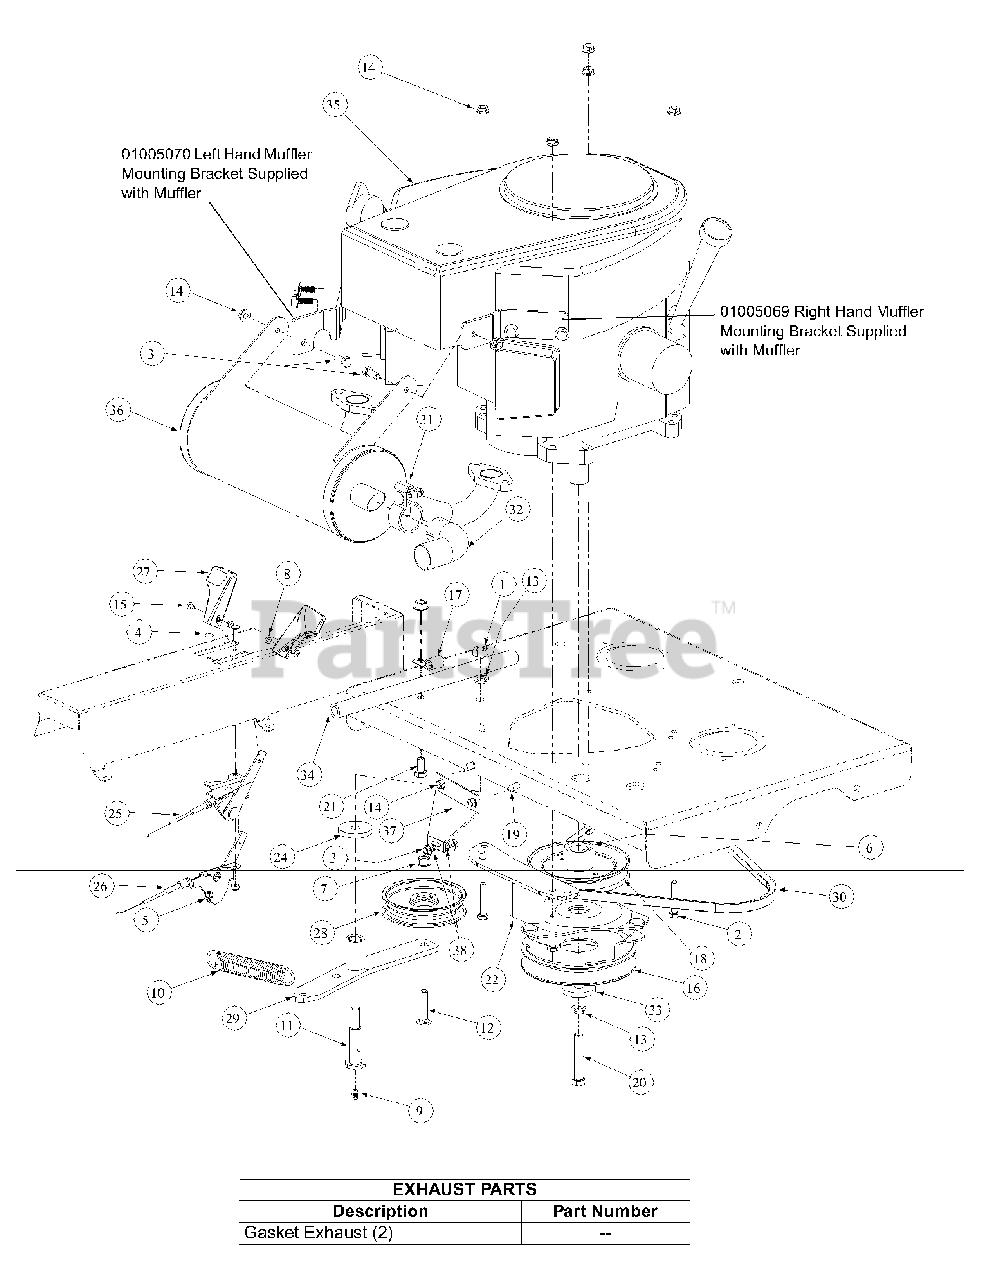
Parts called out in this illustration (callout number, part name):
1	Hex Nut, 7/16-14
2	HHCS, 5/16-18, 1-3/4
3	Hex Cap Screw, 5/16-18 x 3/4
4	Round Hd. Machine Screw, 10-32 x 3/4
5	Lock Nut, Nylon Insert, 10-32
6	Key,1/4 x 1-1/8
7	Flange Lock, Hex Nut, 3/8-16
8	Nut Washer, W/Star, 8-32
9	Grease Fitting, 1/4-28 x 3/16
10	Extension Spring, 1.0 OD x 5.00
11	Shoulder Screw, 7/16-14
12	Hex Carriage Screw, 3/8-16, 1.75
13	Lock Washer, 7/16
14	Hexflange Lock Nut, 5/16-18
15	Machine Screw, 8-32, .375
16	Electric Clutch
17	Clip, Heat Shield Cable
18	Transmission Drive Pulley
19	Carriage Bolt, 5/16-18 x .75 Lg
20	Capscrew, 7/16-20 x3.00
21	Hex Cap Screw, 3/8-16, .750
22	Retainer Clutch Assembly, Ogura
24	Flat Washer, 7/16 ID x 1.75 OD x .25
25	Choke, Control Cable, 43.0
26	Throttle, Control Cable, 39.0
27	Control Throttle Knob
28	Flat Pulley with Flanges
29	Engine Idler Arm Assembly
30	V Belt, A Section x 47.3
31	Tube Clamp, 1.375
32	Muffler Accessory Exhaust Tube
33	Flat Washer, 7/16 IDx 1.750 OD x .250T
34	Oil Drain Hose
35	17HP Kawasaki Engine
36	17HP Kawasaki Exhaust
37	Muffler Bracket
38	Flat Washer, 5/16
